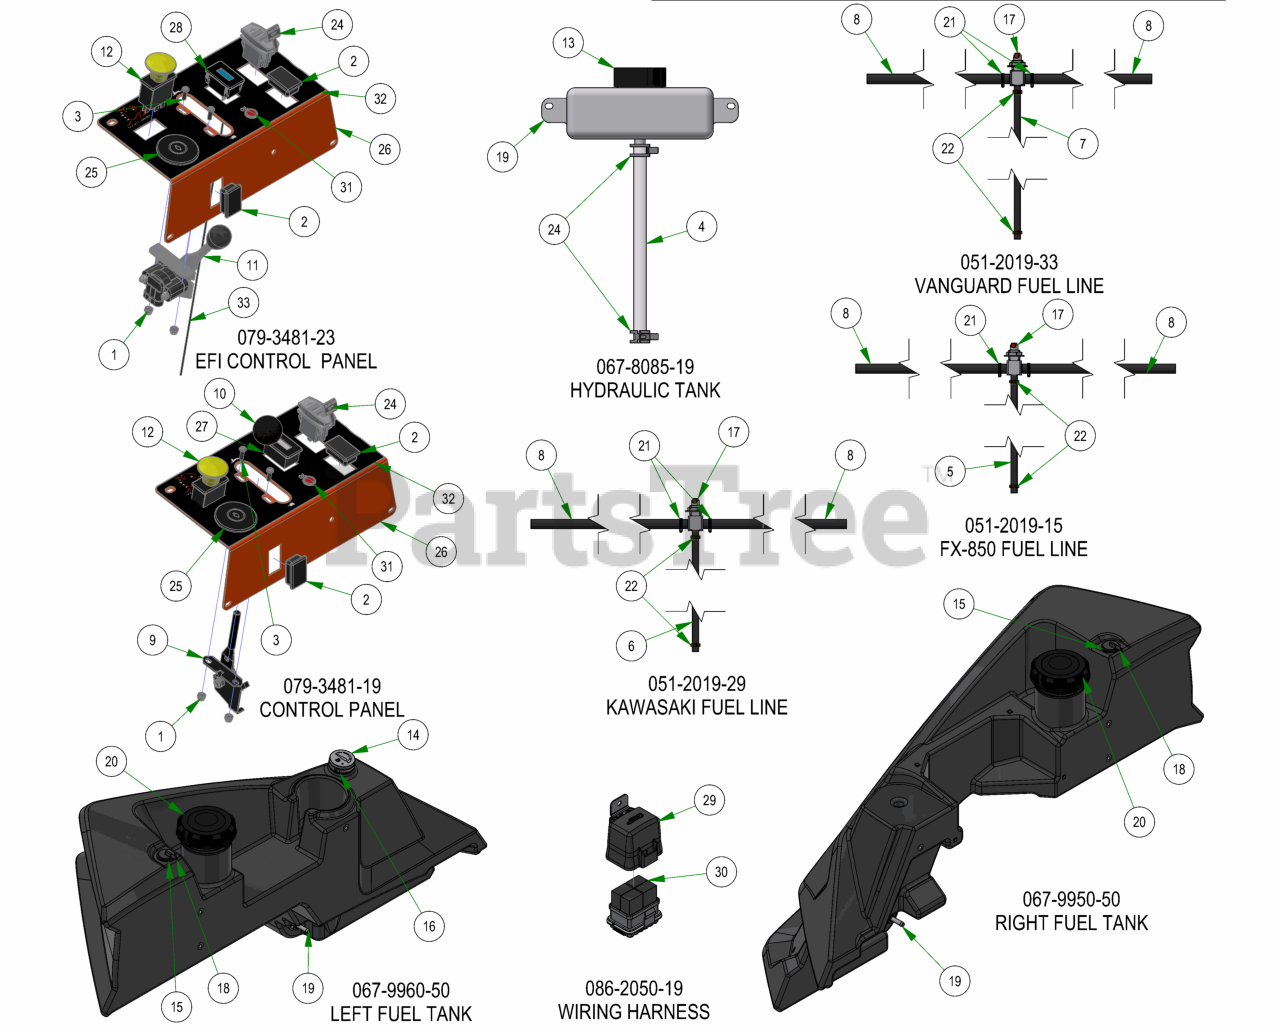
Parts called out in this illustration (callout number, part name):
1	10-24 NYLON INSERT LOCKNUT ZINC
2	Light Plug
3	10-24 X 5/8 BUTTON SOCKET CAP SCREW 18-8 STAINLESS STEEL
4	5/8 Braided Hose
5	1/4" Fuel Line Hose
6	1/4" Fuel Line Hose
7	1/4" Fuel Line Hose
8	5/16" fuel line hose
9	Universal Throttle Head - 2012
10	Throttle Knob
11	Kawasaki \ Kohler Drive By Wire
12	PTO Switch
13	Hydraulic Tank Cap
14	Fuel Gauge with Grommet
15	Roll Over Valve Grommet
16	Fuel Gauge Grommet
17	3 Way Fuel Shut-Off Valve 5/16 x 5/16 x 1/4
18	Rollover Valve
19	Expansion Tank Outlaw
19	Fuel Pick-up
21	5/16 Fuel Line Clamp
22	1/4 Fuel Hose Clamp
24	CTB-23 HOSE CLAMP
25	Ignition Switch
26	2022 Rebel Control Panel
27	Tachometer
28	Hour Meter EFI/EVO
29	Relay Block Cover Replacement Kit
32	2022 Rebel/Rogue Control Panel Decal
33	2023 REBEL/ROGUE Tach Ground Wire Assy
